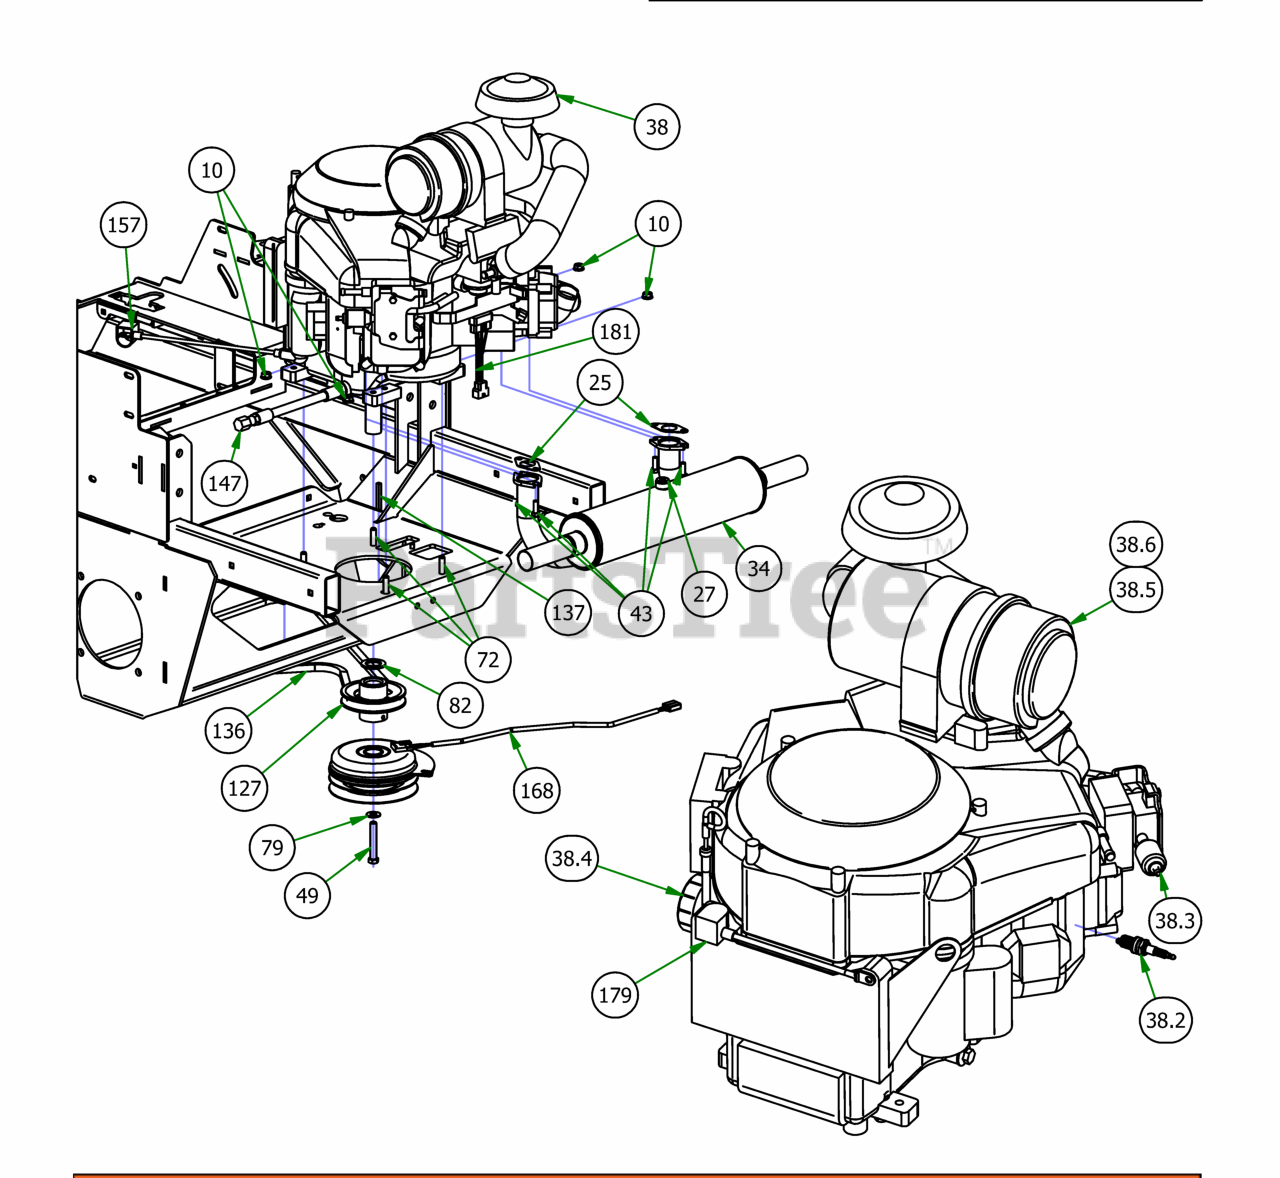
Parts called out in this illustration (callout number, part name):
10	3/8-16 HEX SERRATED FLANGE NUT HARD/ZINC
25	Exhaust Gasket for 23 Vanguard
27	O2 Sensor Plug
34	Muffler for 36Hp Vanguard
38	993cc Vanguard Engine
38.2	Spark Plug
38.3	Universal Inline Fuel Filter
38.4	Oil Filter
38.5	Canister Air Filter- Outer
38.6	Canister Air Filter- Inner
43	Torx Bolt-Exhaust
49	7/16-20 x 2 3/4 Hex C/S GR 8 Yellow Zinc
72	3/8-16 X 1-1/2 HEX CAP SCREW (GR.5) ZINC
79	3/8 FLAT WASHER USS (1" OD) ZINC
82	1 1/8" Flat Spacer
127	4 3/4 Motor Pulley
136	2019 Rebel Pump Belt
137	1/4 x 2 Square key Stock
147	14 mm Oil drain Hose 993cc Vanguard
157	14" Red Battery Cable-Base Outlaw
167	Clutch Assembly
168	Clutch Pigtail
169	2019 Rebel Frame - Powdercoated
179	Starter Cable
181	2019 Harness Adaptor - 36 Vanguard Carberated
